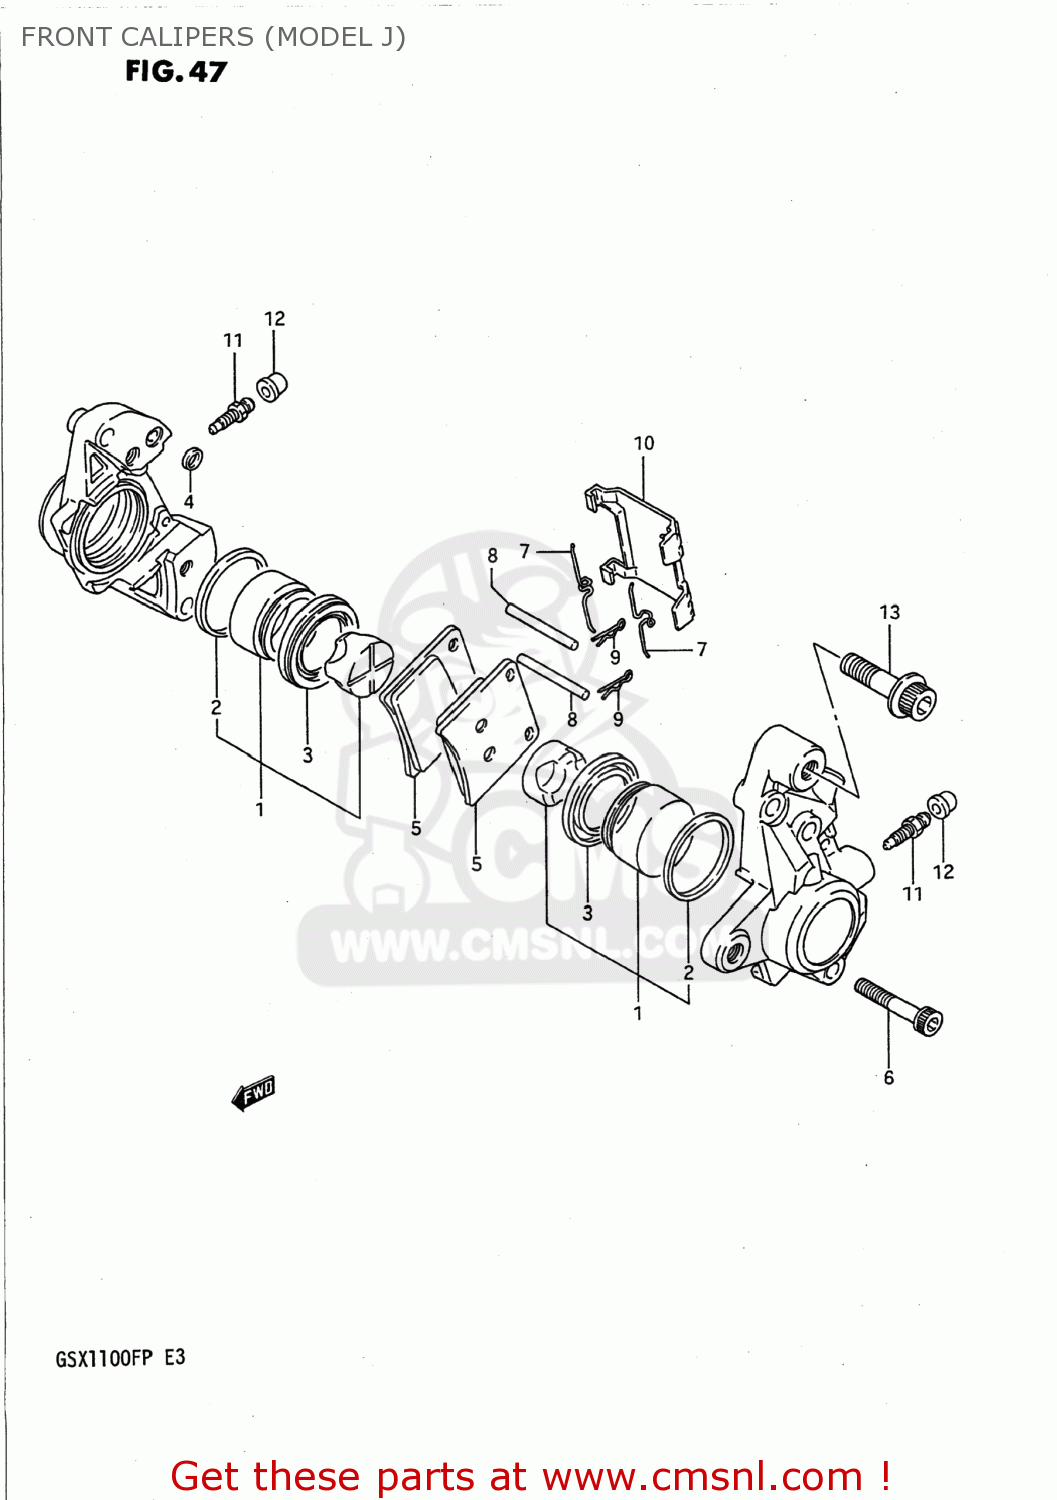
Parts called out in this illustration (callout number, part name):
1	PISTON SET
2	SEAL,PISTON
3	BOOT,PISTON
4	SEAL,JOINT
5	PAD
6	BOLT,CALIPER
7	SPRING
8	PIN,PAD
9	CLIP,PAD PIN
10	COVER,CALIPER
11	BLEEDER
12	CAP,BREATHER
13	BOLT L:38
